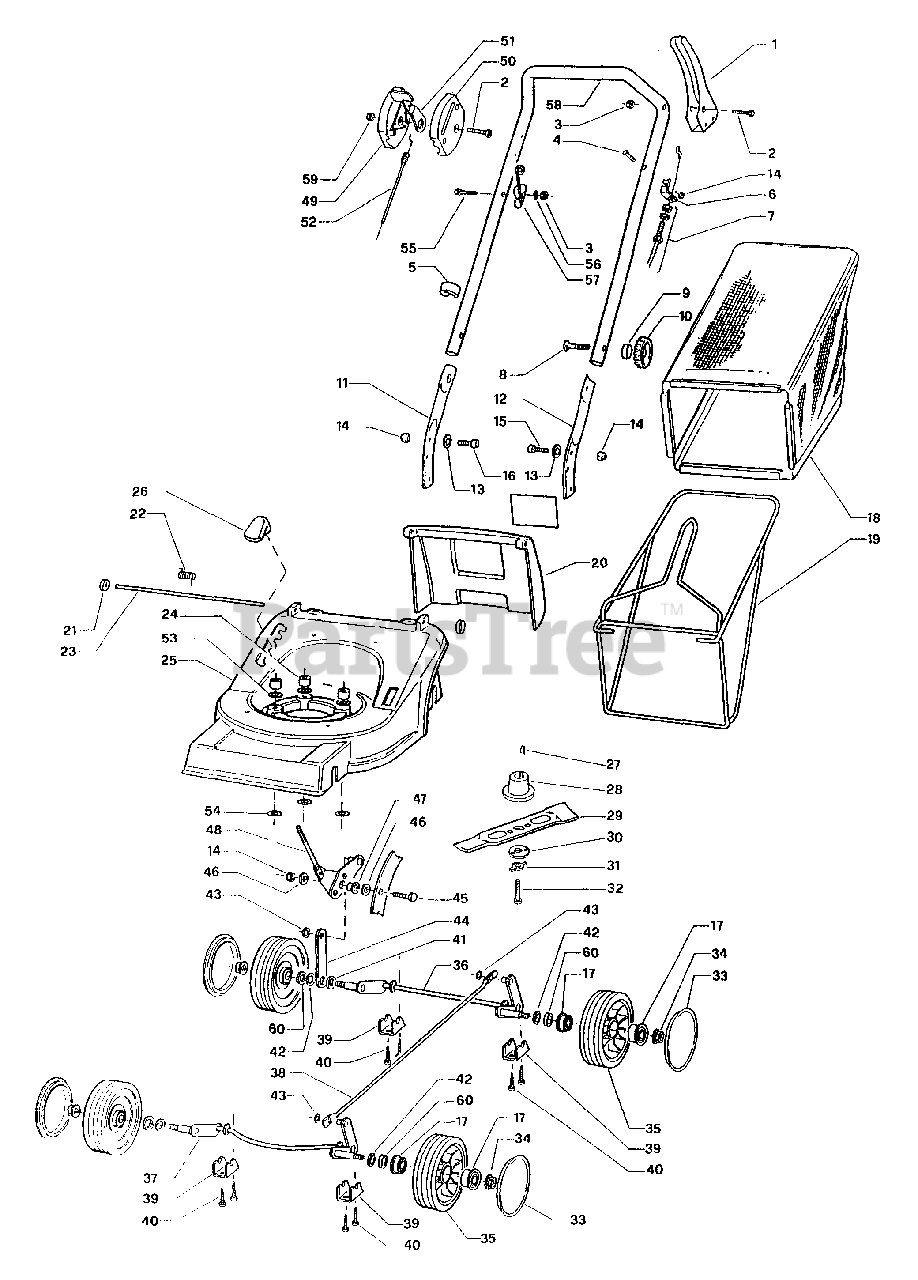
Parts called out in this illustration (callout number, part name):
6	Bracket
7	Cable
11	Handle Lower, Right
12	Handle Lower, Left
17	Bushing
19	Frame, Bag
24	Spacers
28	Bushing
33	Cover Wheel, Front
35	Wheel Rear
36	Pivot, Rear Axle
37	Pivot, Front Axle
38	Link Bar
39	Bracket
44	Bracket
49	Box Half
50	Box Half
57	Washer, Clip
58	Handle Upper
